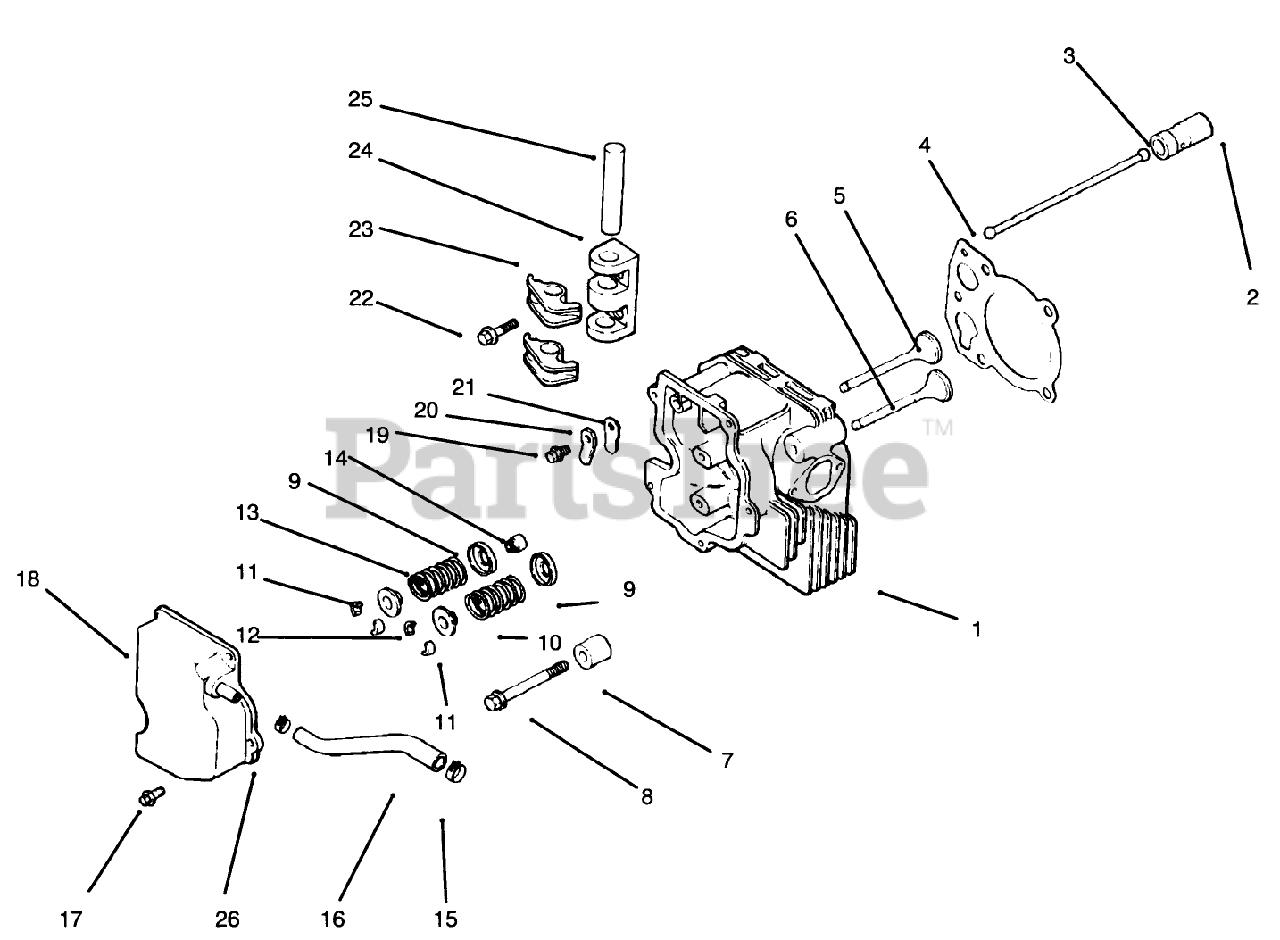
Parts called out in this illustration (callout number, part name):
1	Cylinder Head
2	Lifter-Valve
3	Rod-Push
4	Gasket-Cylinder Head
5	Valve-Intake STD (Only On: 72042, 72063, 72062, 72043)
6	Valve-Exhaust STD (Only On: 72042,72043,72062,72063)
7	Spacer-Head Bolt
8	Screw-Cylinder Head
9	Retainer-Spring
10	Spring-Valve Exhaust (Only On: 72042,72043,72062,72063)
11	Cap-Valve Spring
12	Kit-Retainer
13	Spring-Valve, Intake
14	Seal
15	Clamp
16	Hose-Breather (Only On: 72042, 72063, 72062, 72043)
18	Cover-Valve W/Nipple (Only On: 72042, 72063, 72062, 72043)
20	Retainer-Reed
23	Arm-Rocker
24	Bridge-Rocker Arm
25	Shaft-Rocker Arm
26	Clamp-Hose
